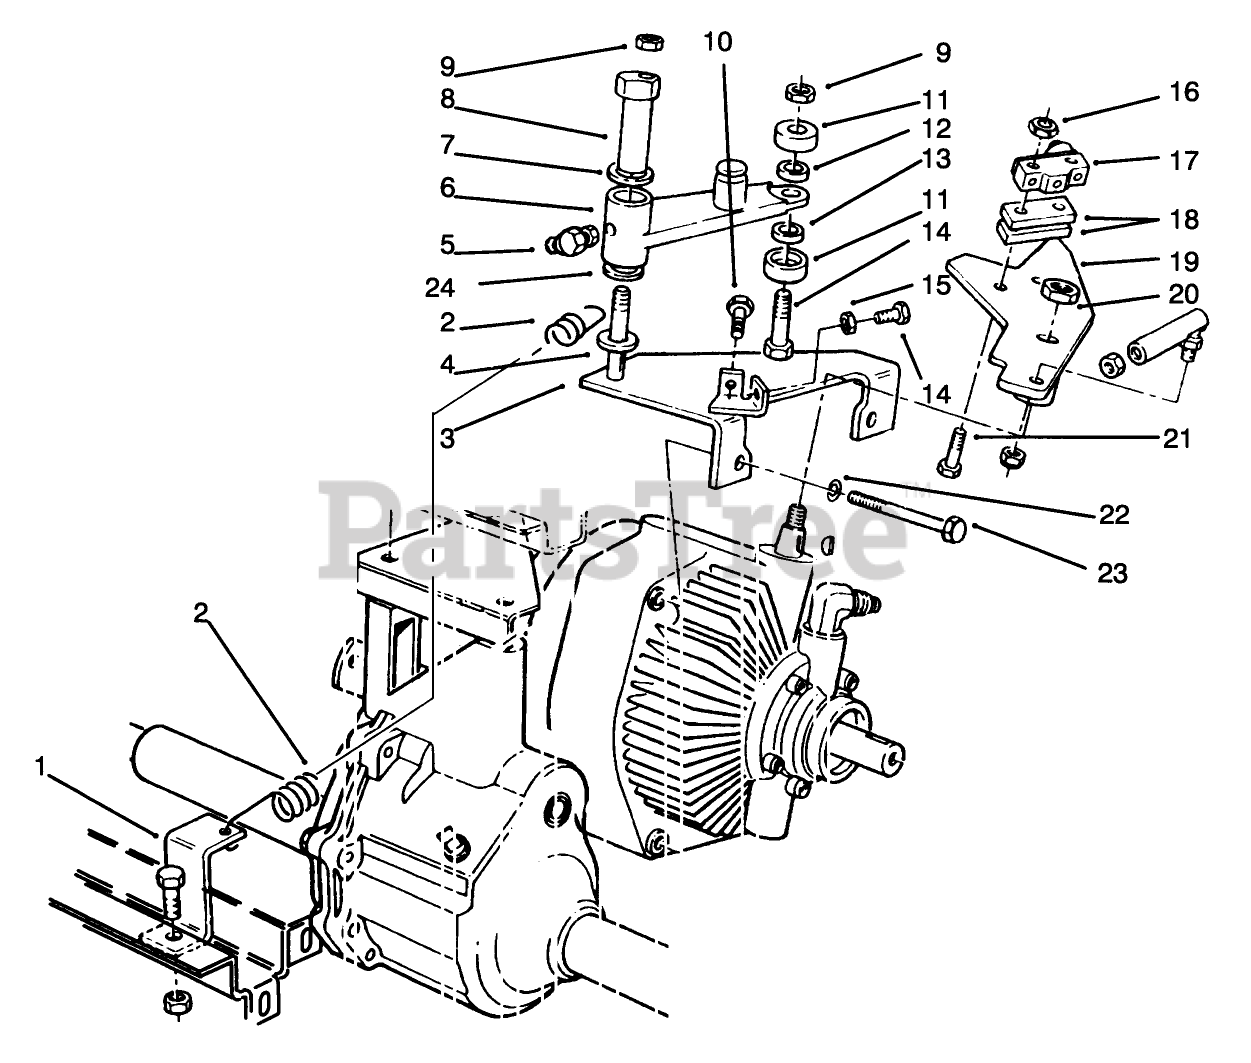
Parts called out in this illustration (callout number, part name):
1	Bracket-Spring
2	SPRING-EXTENSION
3	Plate-Traction
4	WASHER-FLAT
5	FITTING-GREASE
6	Swing Arm Assembly (Incl. Ref.# 24)
7	WASHER-THRUST
8	STUD-TRACTION
9	NUT-LOCK, NI
10	SCREW-HH
11	BEARING-BALL
12	SPACER
13	SPACER-BEARING
14	SCREW-HH
15	NUT-HEX
16	NUT-HEX
17	SWITCH-MICRO
18	PLATE-SWITCH
19	Lever-Traction
20	NUT-LOCK, NI
21	SCREW-PPH
22	WASHER-LOCK
23	SCREW-HH
24	BUSHING-FLANGE
